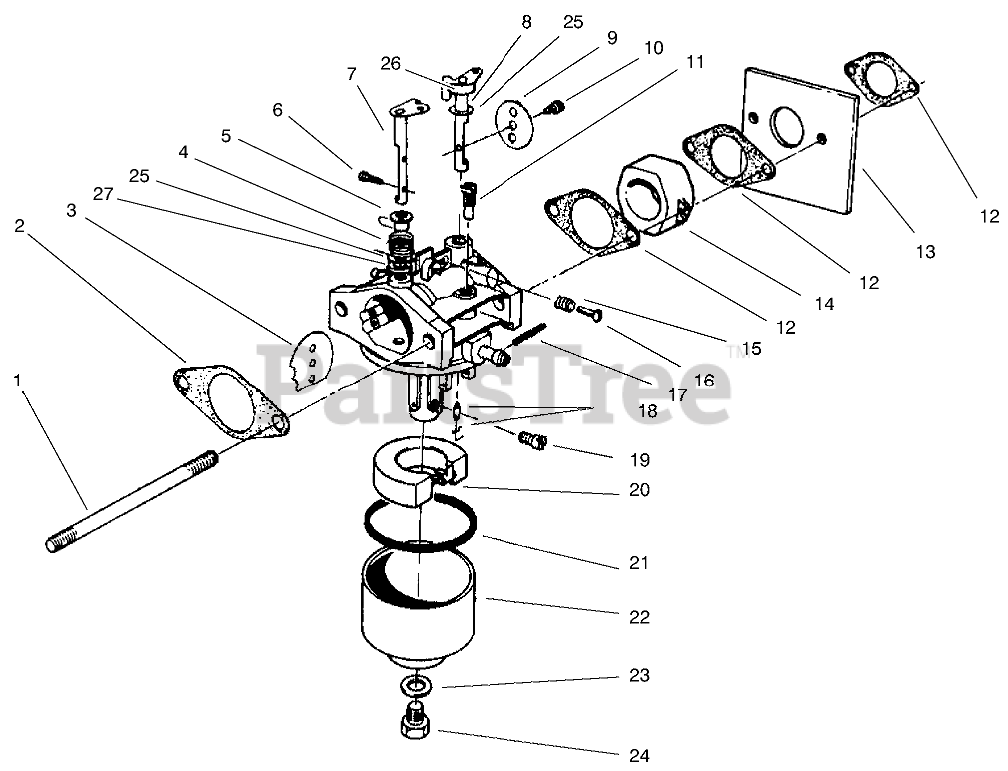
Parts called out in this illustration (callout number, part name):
1	STUD-CARBURETOR
2	GASKET-AIR CLEANER
3	PLATE
4	SPRING
5	BUSHING
6	SCREW
7	SHAFT-CHOKE
8	SHAFT
9	PLATE
10	Screw-Throttle
11	PILOT JET
11	JET-PILOT
12	GASKET-CARB
13	SHIELD-CARBURETOR
14	INSULATOR-CARBURETOR
15	SPRING-PILOT SCREW
16	SCREW
17	PIN-HINGE
18	NEEDLE
19	JET-MAIN
19	JET-HIGH ALTITUDE
20	FLOAT
21	GASKET
22	BOWL - FLOAT
23	GASKET
24	SCREW
27	PACKING
